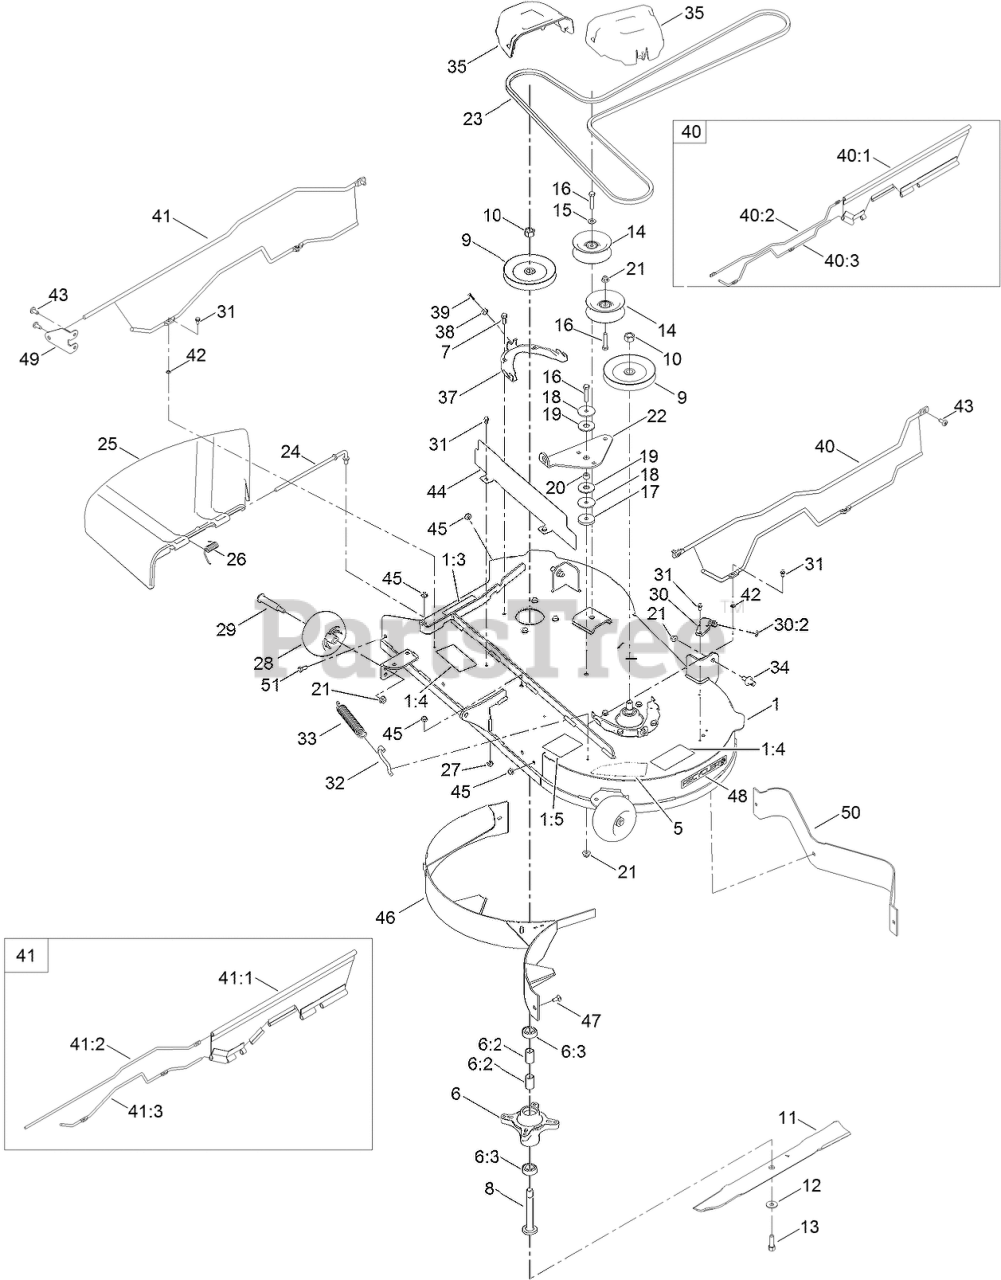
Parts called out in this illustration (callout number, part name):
1	42IN DECK AND DECAL ASM
1:3	DECAL-DANGER
1:4	DECAL-DANGER, DECK
1:5	DECAL-ROUTING, BELT
5	DECAL-DECK
6	SPINDLE ASM
6:2	SPACER
6:3	BEARING-BALL
7	SCREW-TAPTITE
8	SHAFT-SPINDLE
9	Pulley
10	Nut-Hex
11	BLADE-MULCH
12	WASHER-BELLEVILLE
13	SCREW-HH
14	PULLEY-IDLER, FLAT
15	WASHER-FLAT
16	SCREW-HH
17	WASHER-PLAIN
18	Washer
19	WASHER-FRICTION, COMPOSITE
20	SPACER
21	NUT-HF, NI
22	ARM-IDLER
23	V-BELT
24	ROD-PIVOT
25	DEFLECTOR-DISCHARGE
26	SPRING-TORSION
27	NUT-HEX
28	ROLLER-SCALP, ANTI
29	BOLT-SHOULDER
30	FITTING-WASHOUT
30:2	O-RING
31	SCREW-HWH
32	HOOK-RETURN SPRING
33	SPRING-EXTENSION
34	PIN-DECK
35	COVER-BELT
37	BRACKET-COVER, BELT
38	SPACER-NOTCHED
39	SCREW-PPH
40	LEFT GUARD ASM
40:1	GUARD-LEFT
40:2	ROD-TOP, LEFT
40:3	ROD-SUPPORT, LOWER
41	RIGHT GUARD ASM
41:1	GUARD-RIGHT
41:2	ROD-SUPPORT, LOWER
41:3	ROD-TOP, RIGHT
42	NUT-RETAINING
44	SHIELD-FROUNT
45	NUT-HF
46	BAFFLE-RECYCLING
47	BOLT-CARR
48	DECAL-RECYCLER
49	PLATE-MOUNT, GUARD
50	DEFLECTOR
51	SCREW-HH
